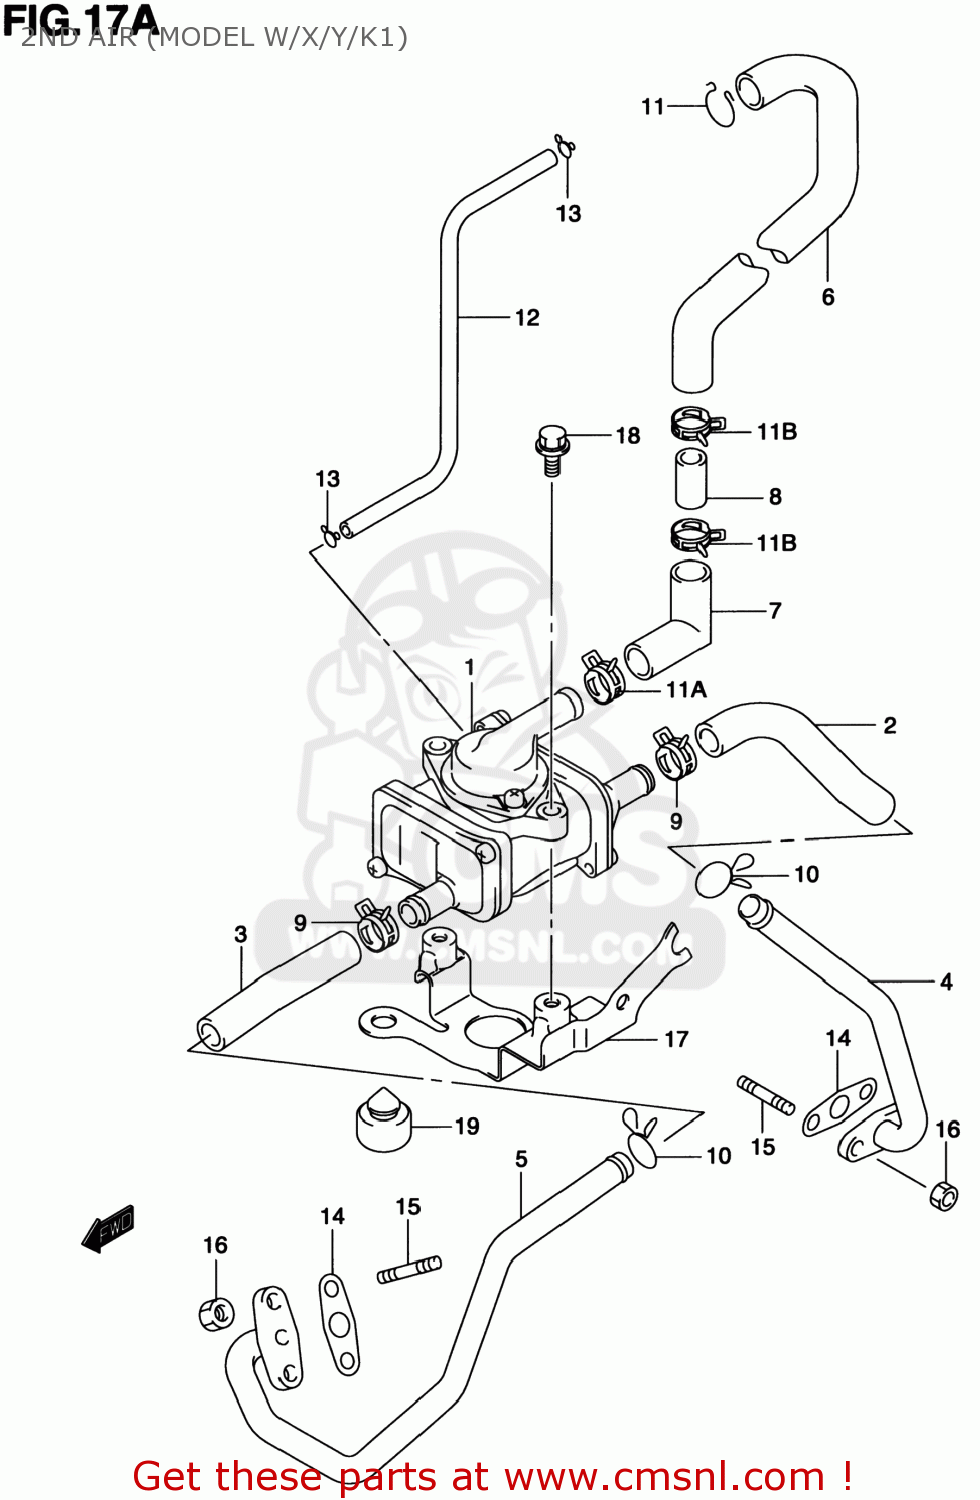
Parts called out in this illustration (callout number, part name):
1	VALVE ASSY,2ND AIR
2	HOSE,2ND AIR VALVE FR
3	HOSE,2ND AIR VALVE RR
4	PIPE COMP,SECOND AIR,FRONT
5	PIPE COMP,SECOND AIR,REAR
6	HOSE,2ND AIR CLEANER
7	HOSE,2ND AIR CLEANER JOINT
8	JOINT,2ND AIR CLEANER HOSE
9	CLIP
10	CLIP
11	CLIP
11A	CLIP
11B	CLIP
12	HOSE(4X7X600)
13	CLIP
14	GASKET,SECOND AIR PIPE (N (NAS)
15	STUD BOLT
16	NUT
17	BRACKET,2ND AIR VALVE
18	BOLT
19	CUSHION(11.5X22X20)
